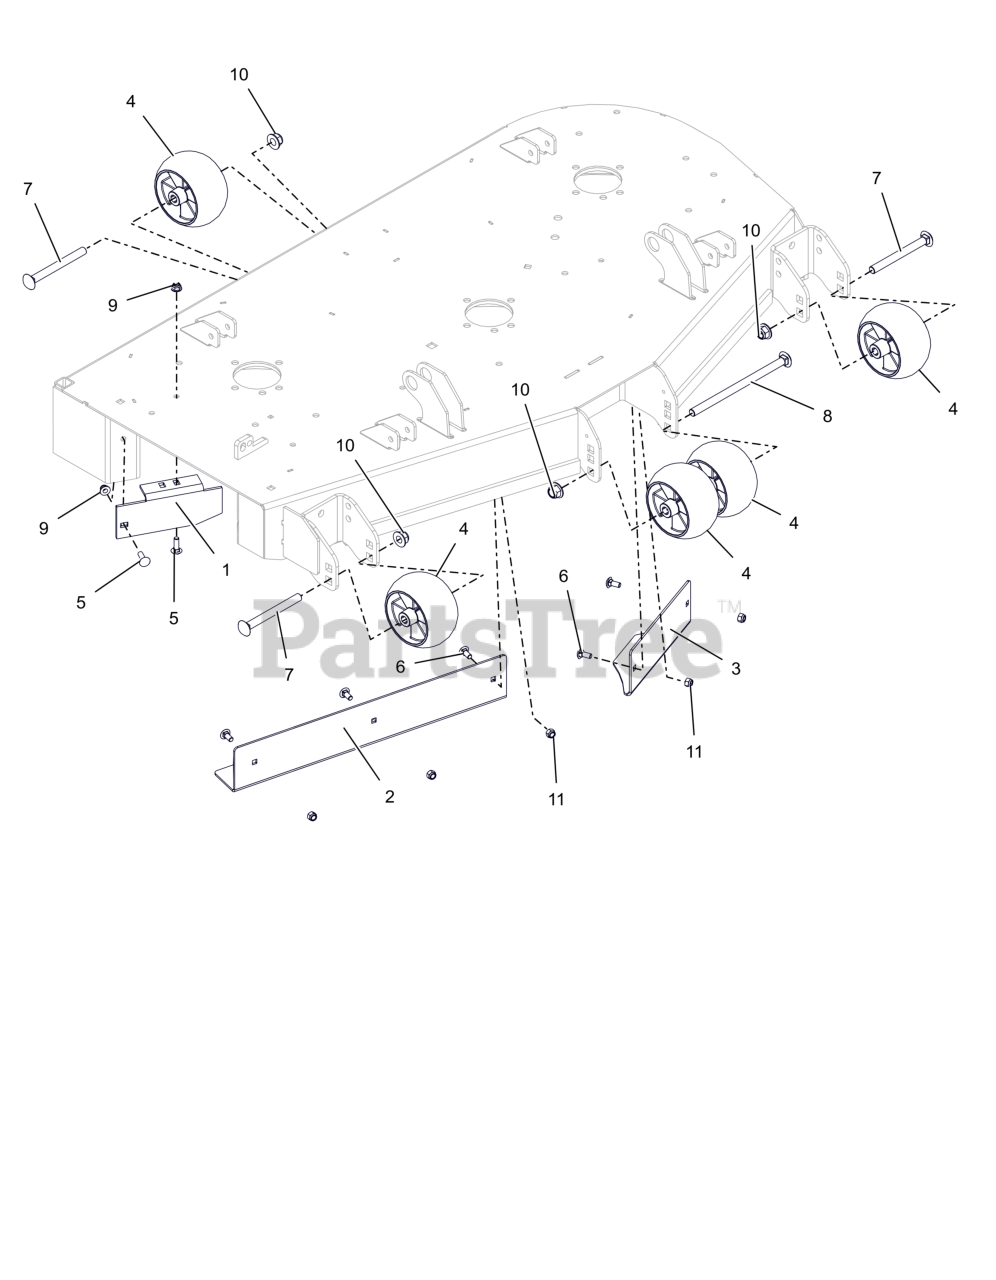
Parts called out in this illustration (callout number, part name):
1	BAFFLE, 44/48" SIDE DISCHARGE
2	BAFFLE, 48" RH VACUUM (ORANGE)
3	BAFFLE, 44/48" LH VACUUM (ORANGE)
4	WHEEL, ANTI SCALP - 5X3 CTR W/RIBS
5	BLT,RHSN .31-18X1.00 G5 ZCC
6	BLT,RHSN .31-18X.75 G5 ZCC
7	BLT, RHSN .50-13X5.00 G5 ZCC
8	BTL,RHSN .500-13 X 8.5S G5 ZCC
9	NUT,LK-NYL-FLG .31-18 G5ZC120
10	NUT,NYL-FLG .50-13 GF ZCC
11	NUT,NYL .31-18 G5 ZCC
